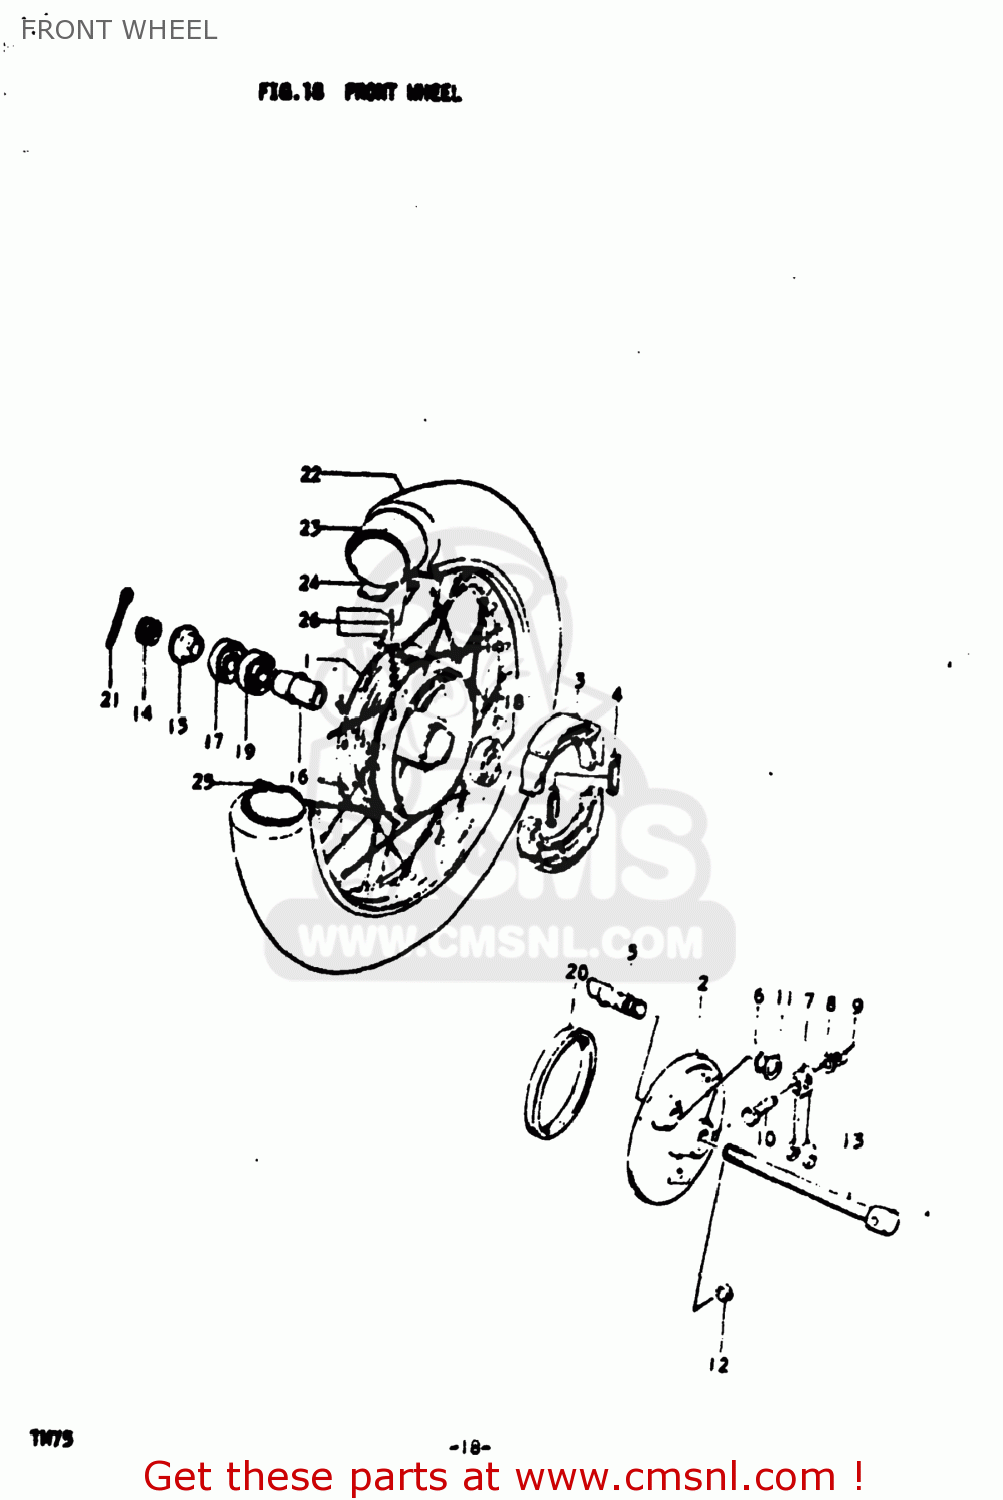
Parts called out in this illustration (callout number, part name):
1	HUB,FRONT
2	PANEL,FRONT HUB
3	SHOE,BRAKE
4	SPRING(L:34)
5	CAM,FR BRAKE
6	O RING(D:2.5,ID:11.4)
7	LEVER,FR BRAKE CAM
8	WASHER
9	NUT
10	BOLT
11	WASHER(12.5X20X1)
12	CAP(OD:17)
13	AXLE,FRONT
14	NUT
15	SPACER,FRONT AXLE,RIGHT
16	SPACER,FRONT HUB BEARING
17	SEAL,OIL(15X31X5)
18	BEARING, LH
19	BEARING
20	OIL SEAL (43X58X7)
21	COTTER PIN
22	TIRE,FRONT
23	TUBE,INNER
24	PROTECTOR,WHEEL,INNER
25	RIM,FRONT WHEEL
26	SPOKE SET,FRONT
